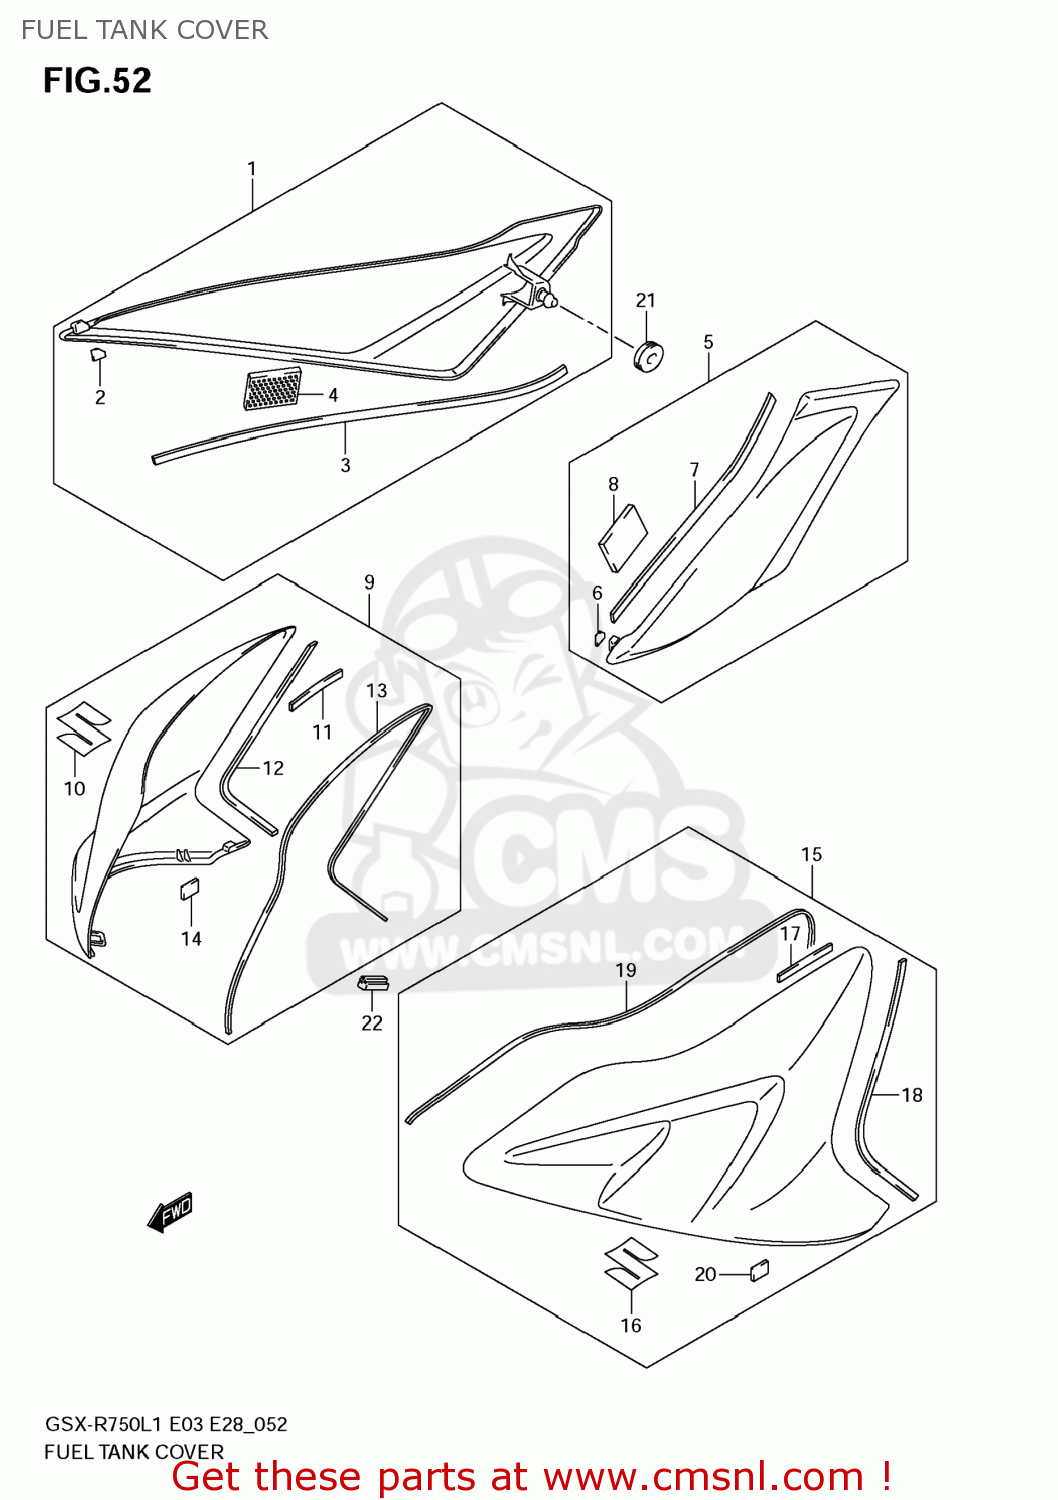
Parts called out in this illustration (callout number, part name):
1	COVER,FUEL TANK SIDE,R
2	CUSHION,FUEL TANK COVER
3	CUSHION,FUEL TANK SIDE COVER
4	FASTENER
5	COVER,FUEL TANK SIDE,L
6	CUSHION,FUEL TANK COVER
7	CUSHION,FUEL TANK SIDE COVER
8	FASTENER
9	COVER,FUEL TAN
10	EMBLEM,S
11	CUSHION,FUEL TANK COVER NO.1
12	CUSHION,FUEL TANK COVER,R NO.2
13	CUSHION,FUEL TANK COVER FR
14	FASTENER,FUEL TANK COVER
15	COVER,FUEL TAN
16	EMBLEM,S
17	CUSHION,FUEL TANK COVER NO.1
18	CUSHION,FUEL TANK COVER,L NO.2
19	CUSHION,FUEL TANK COVER FR
20	FASTENER,FUEL TANK COVER
21	CUSHION,FUEL TANK COVER SIDE
22	CUSHION,FUEL T
